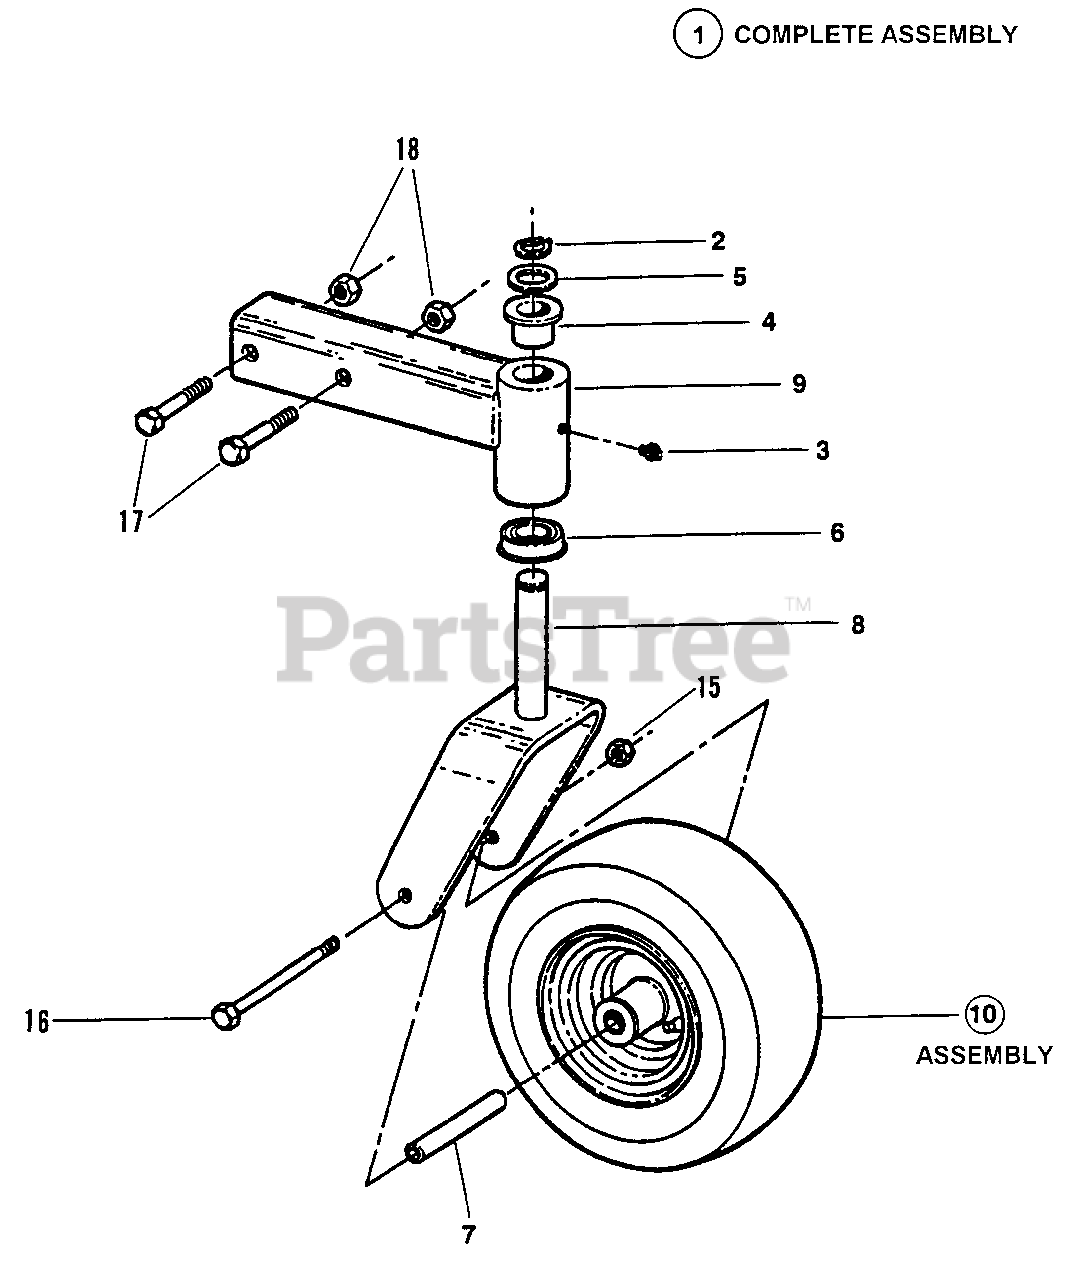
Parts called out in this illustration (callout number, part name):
1	ASSEMBLY, 11" Front Caster
2	RING, 1" External Retaining
3	LUBE FITTING, Straight (press-fit for .187 dia. Hole)
4	BUSHING, Caster
5	BUSHING, 1" Machine
6	BEARING, Flanged Ball
7	TUBE, 5/8" x 18 Ga. Wall x 3.545
8	YOKE, Caster (Weldment)
9	ARM, Telescoping Caster (Weldment)
10	ASSEMBLY, Wheel
15	NUT, 7/16-14 HEX NYLON LOCK
16	SCREW, 7/16-14 x 6" Hex Head Cap, Grade 5
17	BOLT, 1/2-13 X 3" GD5 CZ
18	NUT, 1/2-13 HEX NYLON LOCK
